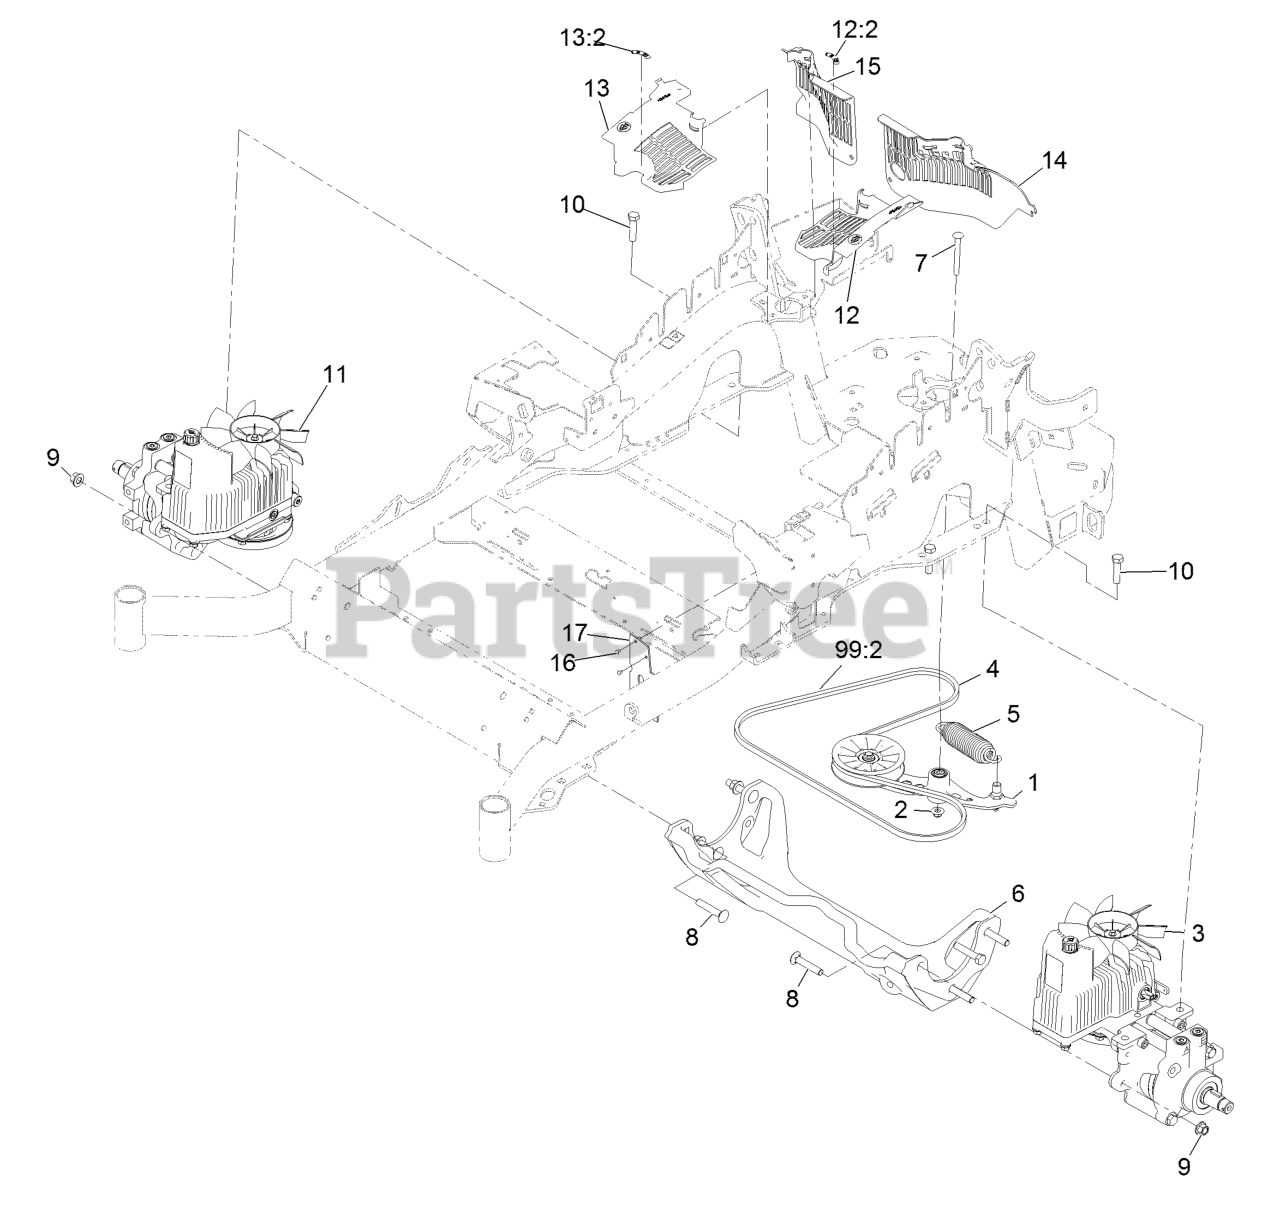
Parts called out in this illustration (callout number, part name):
1	PUMP IDLER ASM
2	Nut-Nyloc 3/8-16 Flg
3	LH HYDRO ASM (12CC W/ SHO
4	BELT
5	SPRING-EXTENSION
6	CRADLE-HYDRO
7	BOLT-SHOULDER, CARRIAGE 3/8-16 X 3 1/2
8	SCREW-CARR
9	Nut-Lock 1/2-13
10	SCREW-HH
11	RH HYDRO ASM (12CC W/ SHO
12	LH HYDRO GUARD ASM
12:2	DECAL-OIL, HYDRO
13	RH HYDRO GUARD ASM
13:2	DECAL-OIL, HYDRO
14	GUARD-HYDRO, REAR (LH)
15	GUARD-HYDRO, REAR (RH)
16	RIVET-POP
17	DEFLECTOR-AIR FLOW
99:2	BELT
